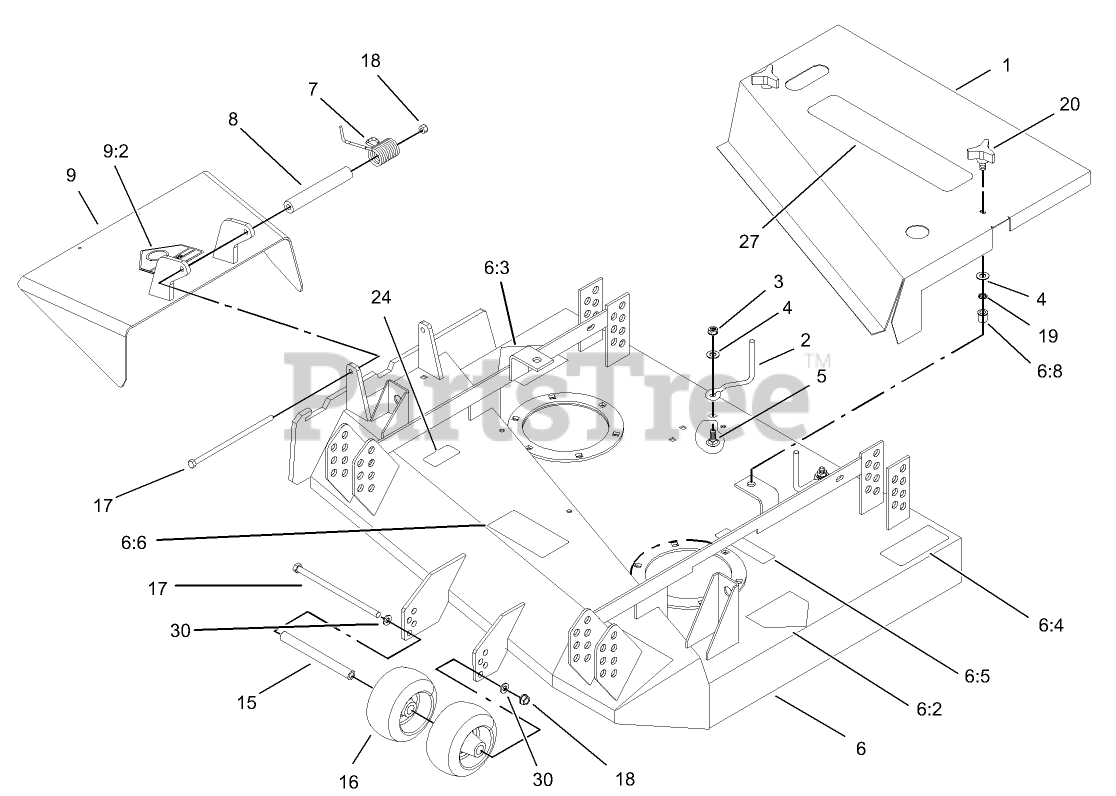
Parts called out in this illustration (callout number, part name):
2	ROD-BELT
3	NUT-HF
4	WASHER-FLAT
5	SCREW-CARR
6	Deck ASM
6:2	DECAL-DANGER
6:3	DECAL-DANGER
6:4	DECAL-TORQUE
6:5	DECAL-DANGER
6:6	DECAL-DANGER, THROWN OBJECT
6:8	INSERT-NUT
7	SPRING-TORSION
8	SPACER
9	DEFLECTOR ASM
9:2	DECAL-DANGER
15	SPACER-WHEEL
16	WHEEL-GAGE
17	SCREW-HH
18	NUT-LOCK, NI
19	RING-RETAINING
